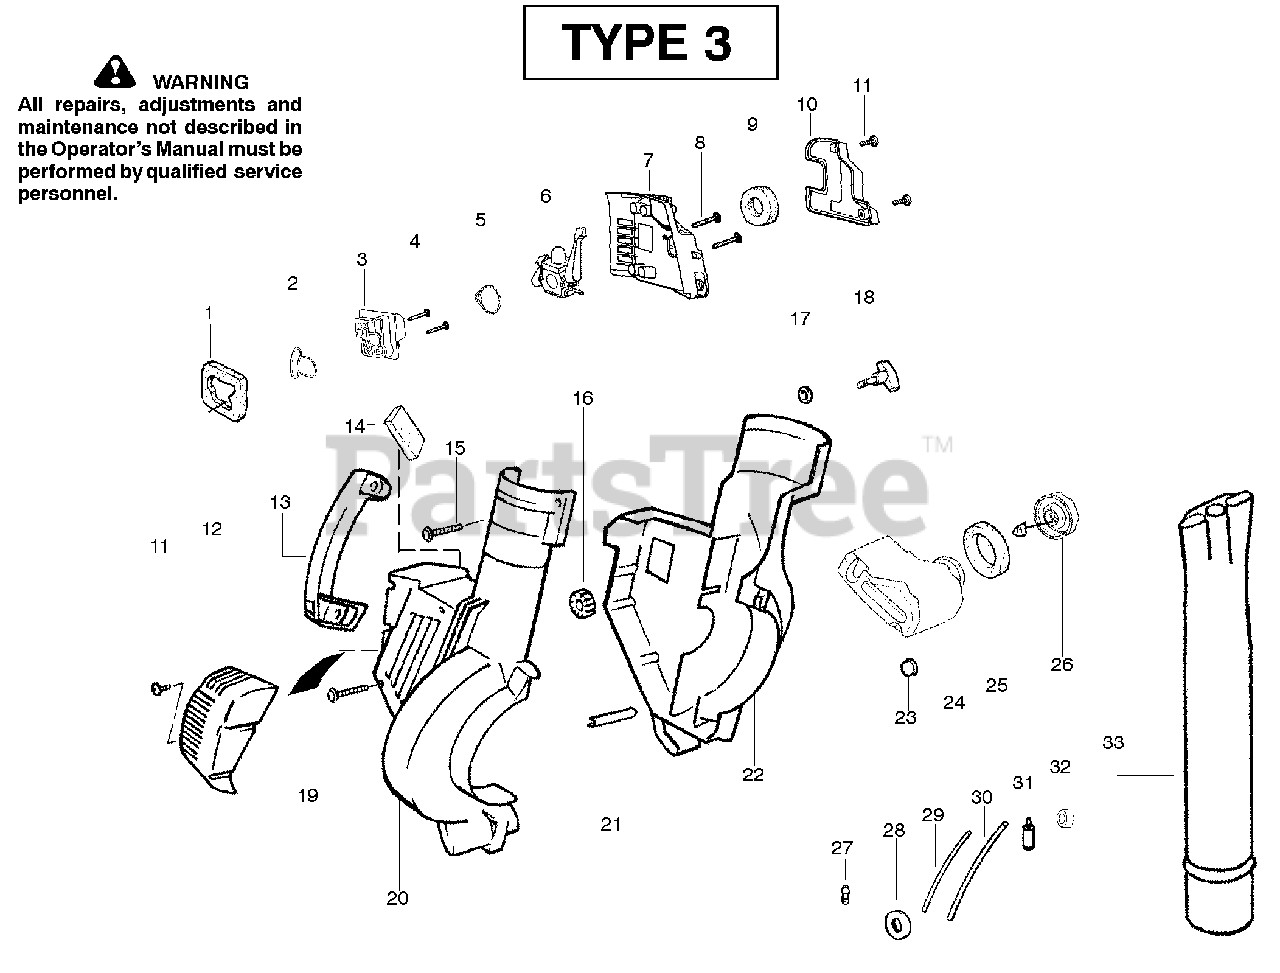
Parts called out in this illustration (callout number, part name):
1	Air Dam (kit)
2	Gasket-Adapter (kit)
3	Carburetor Adaptor
5	Gasket-Carburetor (kit)
6	Kit-Carb Ass'y. Zama-(C1Q-W11C)
10	Cover-Air Filter
12	Guard-Muffler
14	Foam - 71.12mm (kit)
19	Tape-Reflector (kit)
21	Guide-Starter Rope
23	Isolator-Crankcase
24	Assy-Fuel Tank
25	Gasket-Fuel Tank
26	Fuel Cap w/Retainer
27	Fitting-Fuel Line
28	Grommet-Shroud
29	Kit-Line Carb/Purge
30	Kit-Line Tank/Purge
31	Assy-Fuel Pick-up
32	Grommet-Fuel line (kit)
